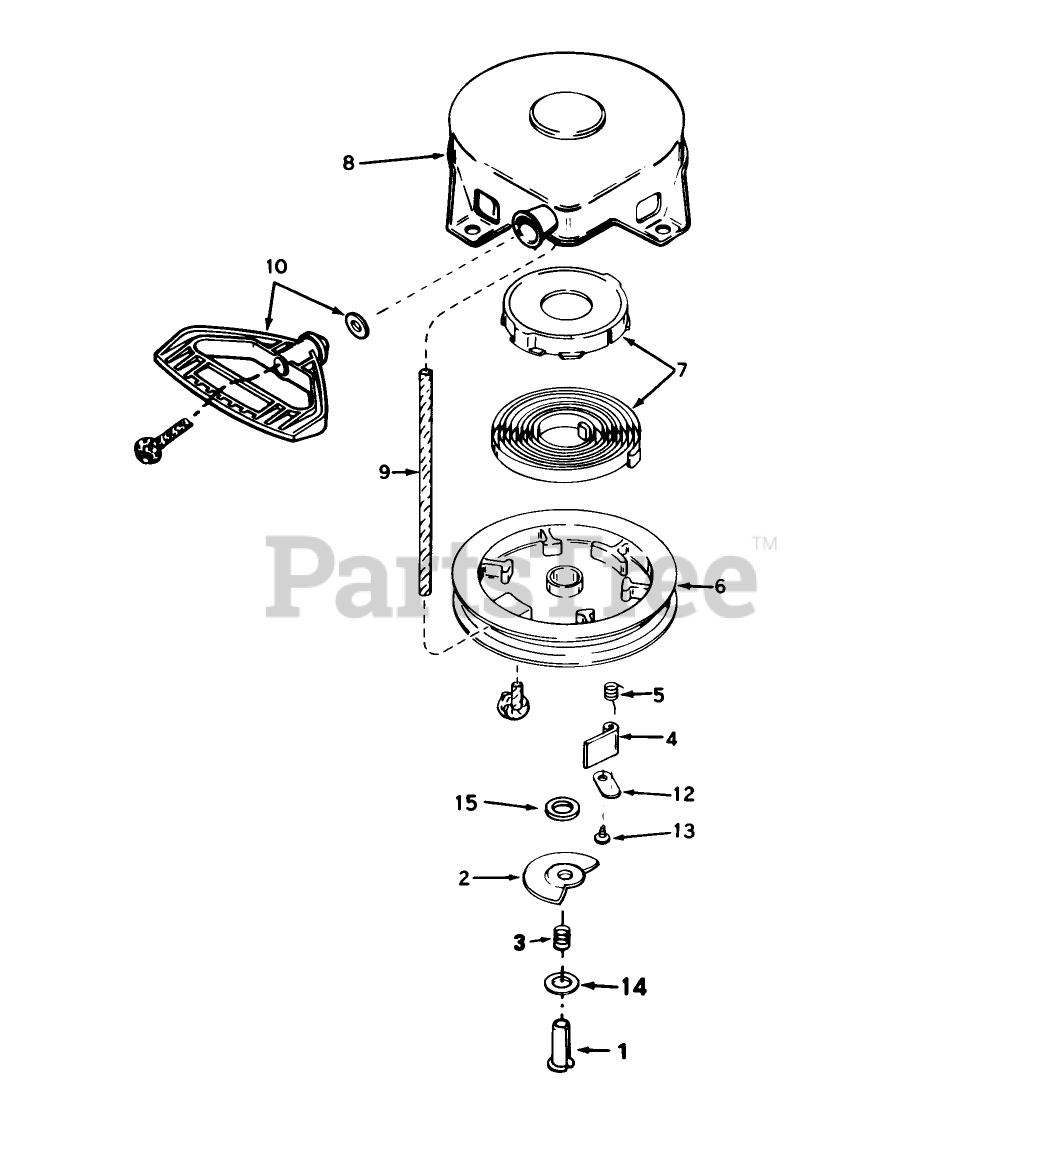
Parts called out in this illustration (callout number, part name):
1	Pin Spring
2	Washer
3	Brake Spring
4	Dog-Starter
5	Spring-Dog
6	Pulley
7	Spring Keeper Assy
8	Housing-Starter
9	Rope-Starter
10	Handle-Starter, Mitten Grip
12	Retainer-Dog
13	Screw
14	Washer
15	Washer
